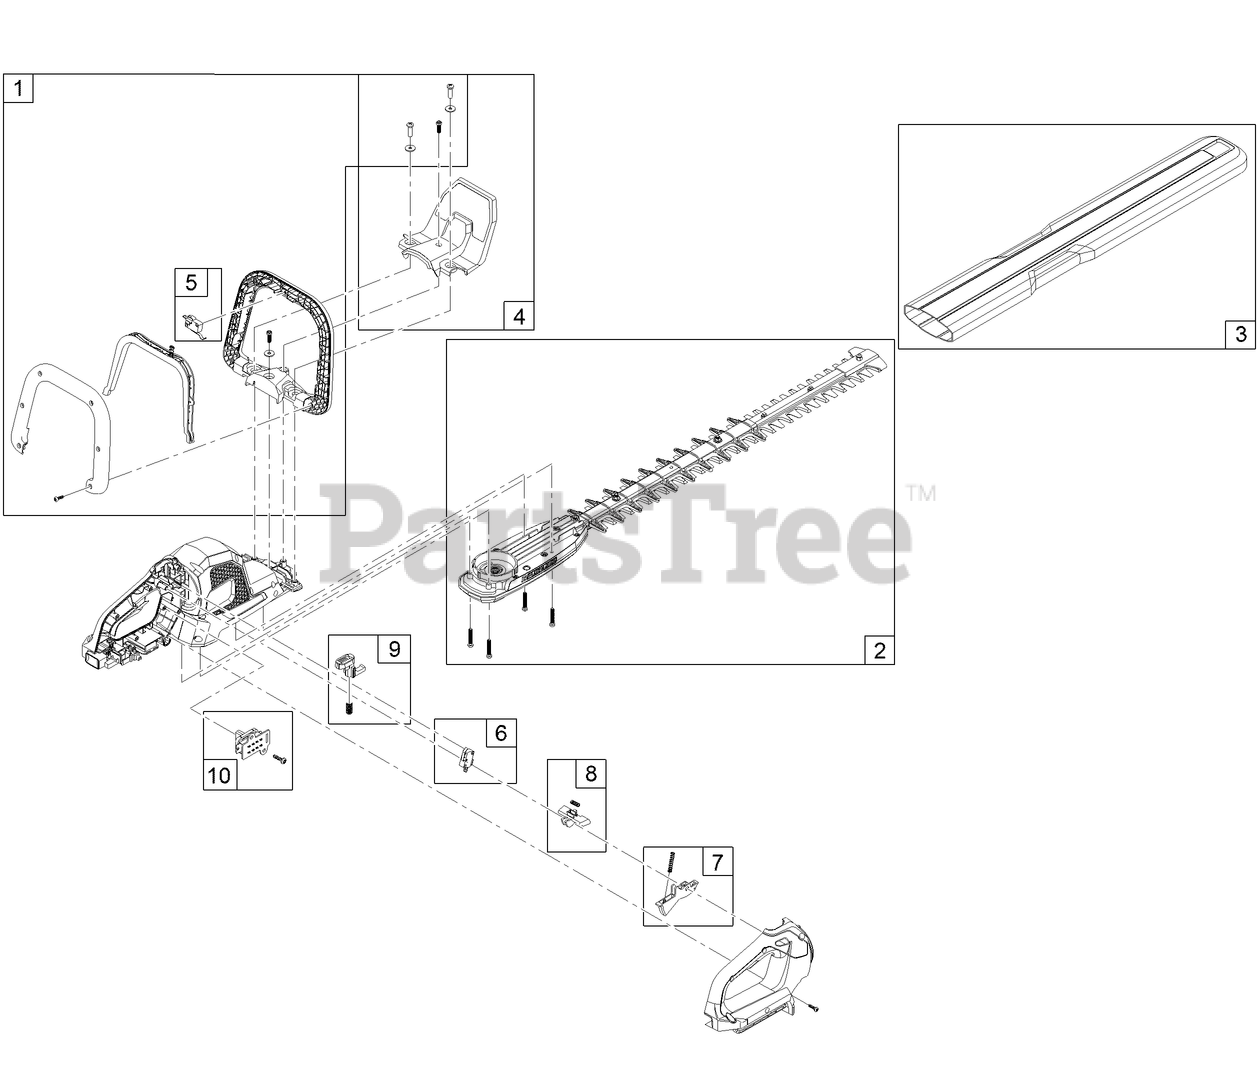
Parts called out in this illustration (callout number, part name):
1	ASSIST HANDLE ASM
2	BAR, BLADES AND GEAR CASE ASM
3	COVER-BAR
4	GUARD ASM
5	SWITCH-ASSIST HANDLE
6	SWITCH-MOTOR
7	TRIGGER-SPRING ASM
8	TRIGGER-SLIDE LOCK ASM
9	BUTTON-HANDLE ROTATION ASM
10	SWITCH-SPEED CONTROL ASM
